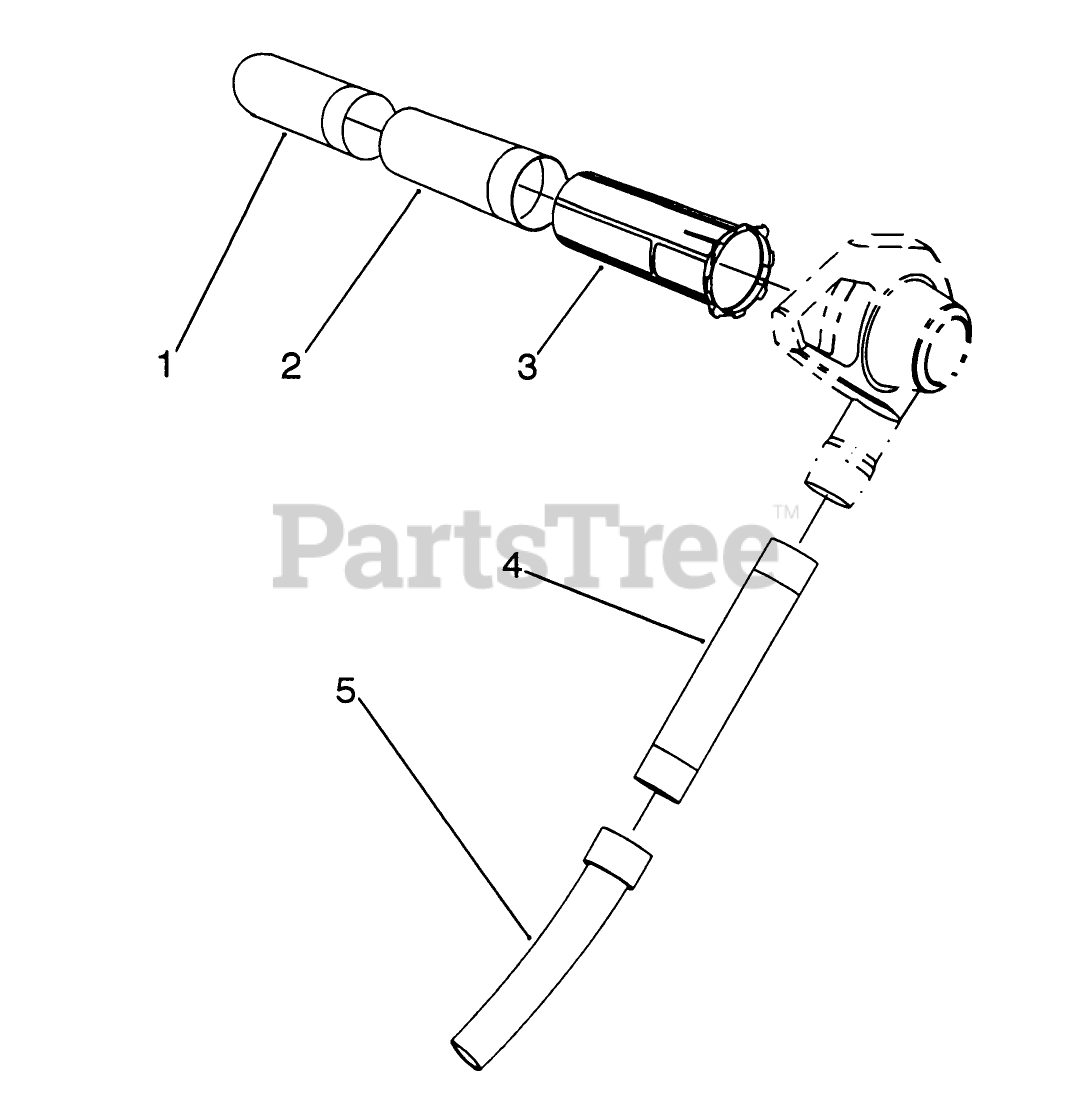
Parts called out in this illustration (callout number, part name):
1	LOWER VAC TUBE
2	MIDDLE VAC TUBE
3	UPPER VAC TUBE
4	BLOWER TUBE
5	MID BL-DISCHARGE TUBE
